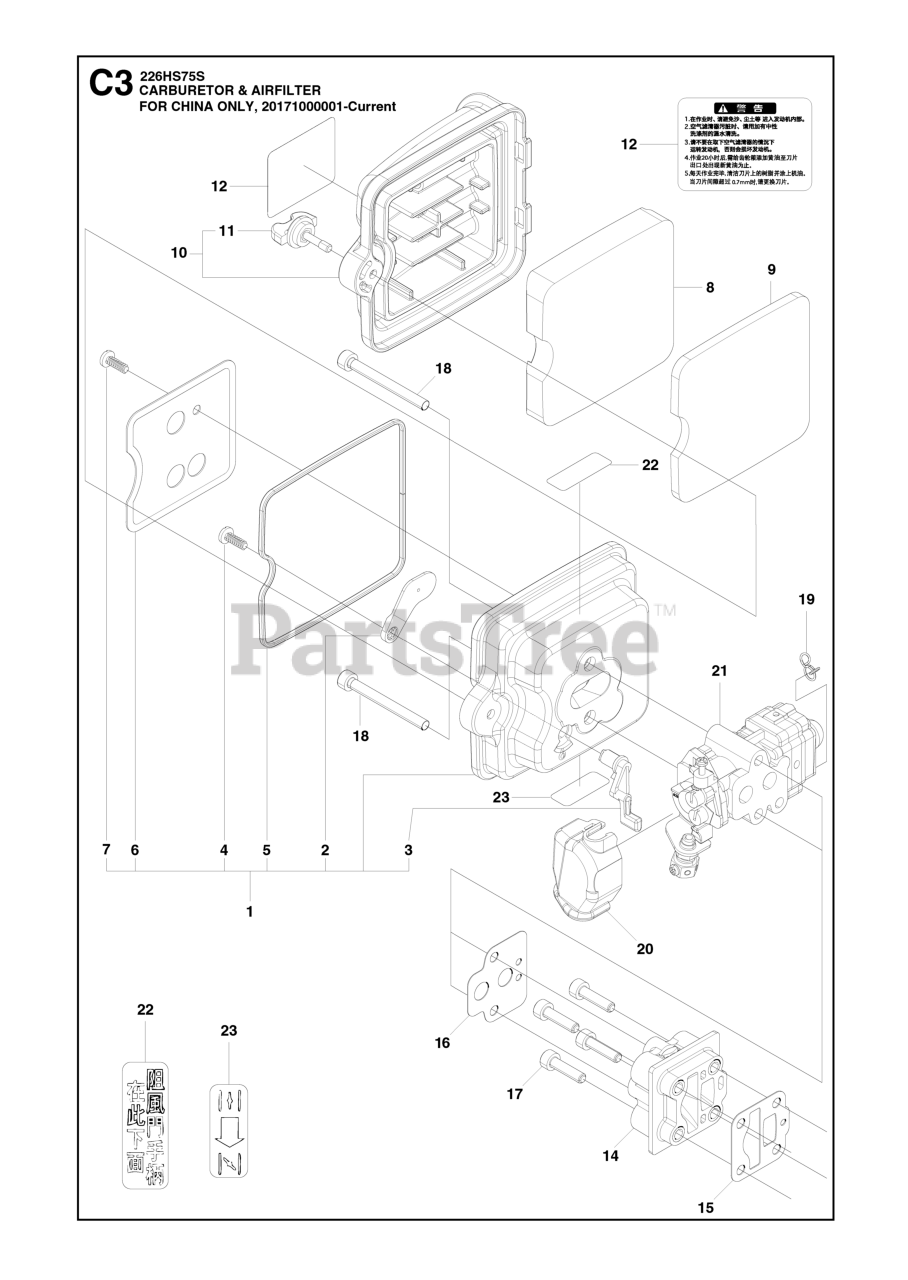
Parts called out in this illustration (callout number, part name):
1	FILTER HOUSING
2	PLATE.CHOKE
3	LEVER CHOKE
8	FILTER FOAM
10	COVER ASSY
12	LABEL.CAUTION
16	GASKET, CARB (RPLS T155113131)
21	CARBURETTOR ASSY
22	LABEL.CHOKE
